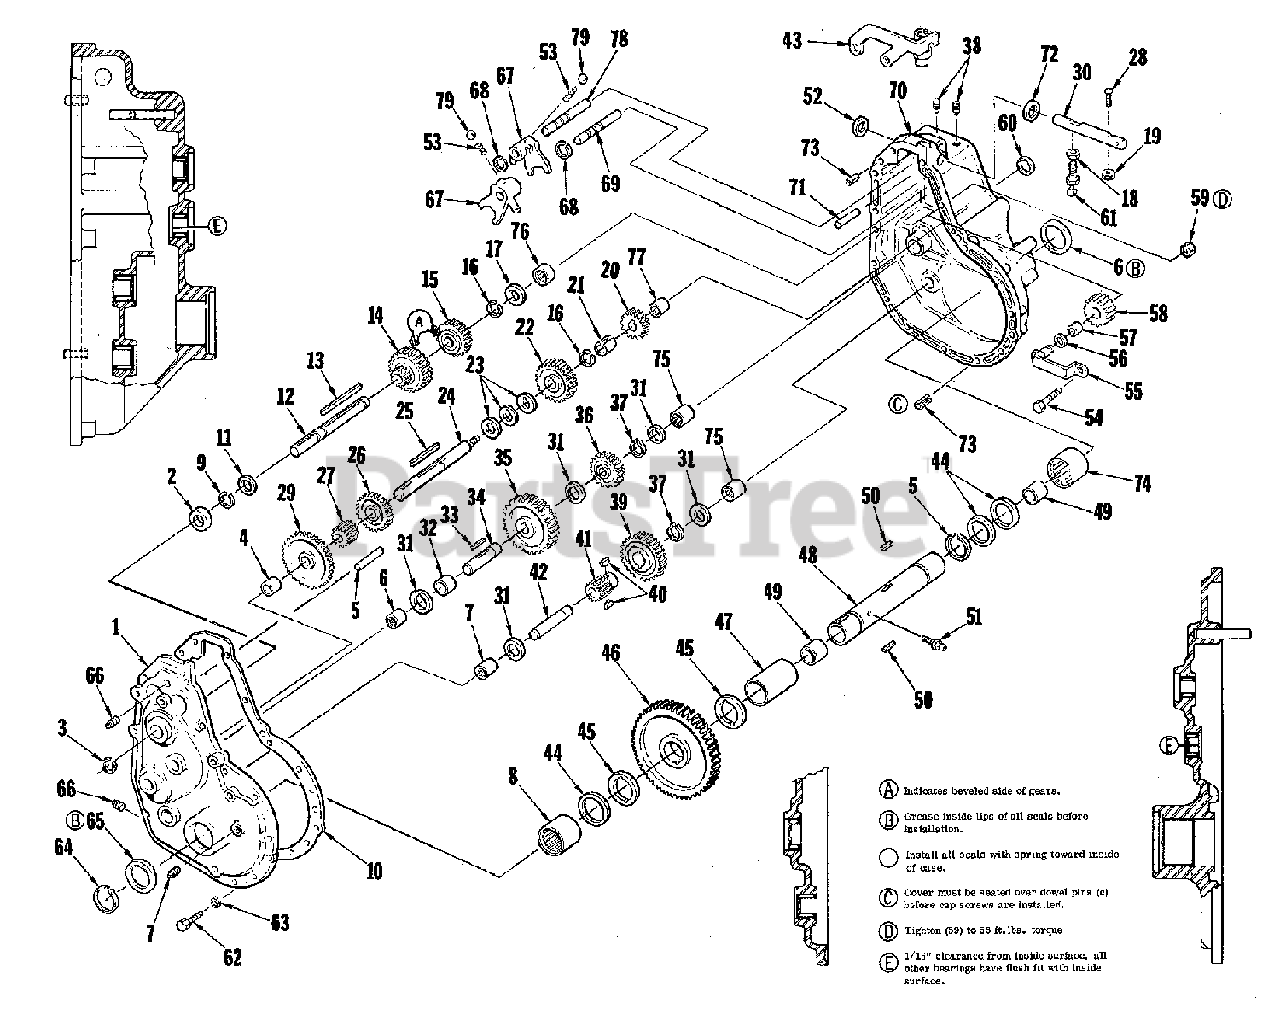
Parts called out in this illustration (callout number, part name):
1	COVER, Gear Case Sub Assembly
3	RING, Retaining
4	BEARING, Needle
5	ROLL PIN ASSEMBLY
6	BEARING, Needle
7	BEARING, Needle
8	BEARING, Needle
9	RING, Retaining
10	GASKET, Gear Case
12	SHAFT, Pulley
14	PINION ASSEMBLY, I & II
15	PINION ASSEMBLY, Rev. & II
16	RING, Retaining
18	NUT, Full Hex, 3/8-24
19	NUT, Hex Jam Fin, 5/16-18
20	PINION, Reverse
22	GEAR, Driven II
23	SPACER, Transmission Gear
24	SHAFT, 1st Intermediate
26	PINION, Driven III
27	PINION, 1st Intermediate
28	BOLT, Round Head, 5/16-18 x 1
29	GEAR, Driven 1st
34	SHAFT, 2nd Intermediate
35	GEAR, 2nd Intermediate
36	PINION, 2nd Intermediate
37	RING, Retaining
38	SCREW, Set Socket Head, 5/16-18 x 1/2
39	GEAR, 3rd Intermediate
40	KEY, Woodruff #6
41	PINION, 3RD Intermediate
42	SHAFT, 3rd Intermediate
43	SUPPORT, Switch
45	WASHER, Axle Tube
46	GEAR, Driven
47	SPACER, Axle Tube
48	TUBE & BUSHING ASSEMBLY
51	FITTING, Lube
54	SCREW, Hex Head Cap, 3/8-16 x 1-1/4
55	PIN, Assembly, Reverse Gear
57	SPACER, Reverse Gear
58	GEAR, Reverse
59	NUT, Hex Lock Fin
62	SCREW, Hex Head Cap, 5/16-18 x 1
63	WASHER, Lock, 5/16
68	RING, Retaining
69	SHAFT, Shifter, Hi-Low
70	CASE, Gear Sub Assembly
71	ROLL PIN SUB ASSEMBLY
74	BEARING, Needle
75	BEARING, Needle
76	BEARING, Needle
77	BEARING, Needle
78	SHAFT, Shifter, Reverse Medium
79	BALL, Shift Lock
